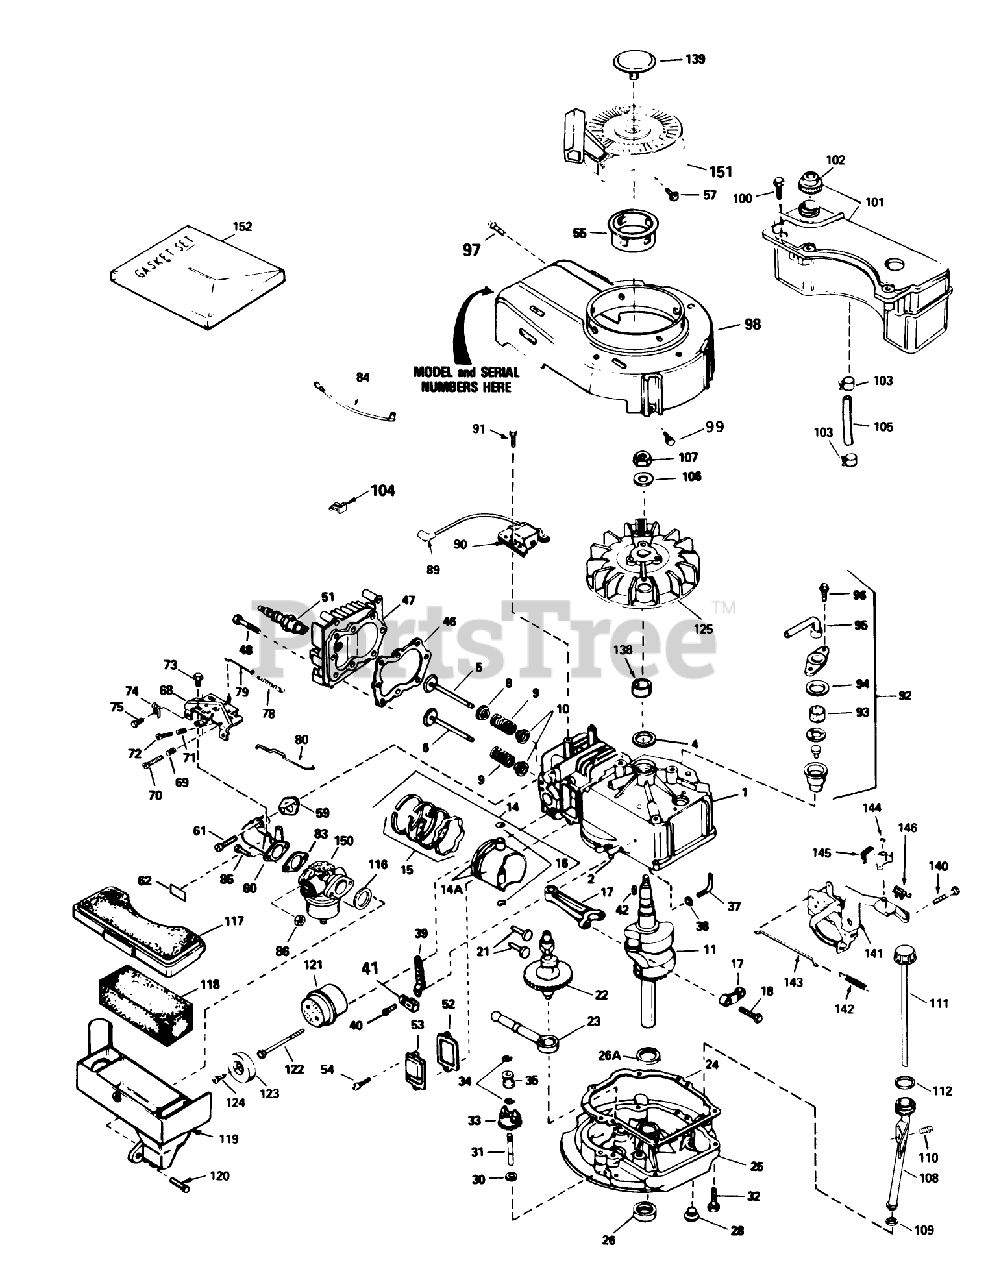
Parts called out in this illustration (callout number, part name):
1	Cylinder Assy. (Incl. #24)
2	Pin-Dowel
4	Seal-Oil
5	Valve, Intake (Std.) (Incl. Ref. #40)
5	Valve, Intake (1/32" oversize)(Incl. No. 40)
6	Valve, Exhaust (Std.)(Incl. No. 40)
6	Valve, Intake (1/32" oversize)(Incl. No. 40)
8	Seal Assy., Intake
9	Spring-Valve
10	Cap-Valve, Spring
11	Crankshaft
14	Piston-Pin Ring Assy. (Std.)(Incl. Ref. #16A, 17 18)
14	Piston-Pin Ring Assembly (.010 oversize)(Incl. Ref. #16A, 17 18)
14	Piston, Pin Ring Assy. (.020 Oversize)(Incl. Ref. #13A, 14, 15)
14A	Piston Pin Assy. (Std.)(Incl. Ref. #14)
14A	Piston Pin Assembly (.010 oversize)(Incl. Ref. #18)
14A	Piston Pin Assy. (.020 Oversize) (Incl. Ref. #14)
15	Ring Set-Piston (Std.)
15	Ring Set, Piston(.0100versize)
15	Ring Set (.020" OS)
16	Ring-Retaining, Piston Pin
17	Rod Assy., Connecting (Incl. Ref. #17)
18	Bolt-Rod, Connecting
21	Lifter-Valve
22	Camshaft(Mech.Comp. Release)
23	Oil Pump ASM
24	Gasket
25	Flange-Mounting (Incl. Ref. #26, 27 39)
26	Seal-Oil
26A	Washer-Thrust
28	Plug Oil Drain
30	Washer-Flat
31	Shaft-Governor
32	Screw (1/4-20 x 1-1/4)
33	Governor Gear ASM
34	Ring-Retaining
35	Spool-Governor
37	Rod, Governor (Incl. No. 36)
38	Washer-Flat
39	Governor Lever
40	Screw
41	Clamp-Lever, Governor
42	Key-Flywheel
46	63573 GIL 42 SNWTHW
47	Head-Cylinder
48	Screw
51	Spark Plug-Resistor (R J19 L M)
52	Gasket-Breather
53	Cover-Valve
54	Screw
55	Hub-Starter
57	Screw, Hex Hd.
59	Gasket-Intake
60	Pipe-Intake (Incl. Ref. #59)
61	Screw (1/4-20 x 1)
62	Decal-Primer
68	51089 SUPP TO MANUA
69	61709/GIL1515A/95-5
70	Screw
71	Spring-Compression
72	Screw
73	Screw (10-24 x 9/16)
74	Conduit
75	Screw (10-32 x 3/8)
78	Spring Governor
79	2035A67 ADD.ASSEMBL
80	Link-Throttle
83	Gasket
84	Ground Wire
86	Nut and Lock Washer (1/4-28)
89	Cover-Spark Plug
90	Solid State
91	Screw
92	Breather Assy. (Incl. Ref. #46 thru 51)
93	Element-Breather
94	Gasket-Breather
95	Tube, Breaker
96	Screw (10-24 x 9/16)
97	Screw (10-24 x 9/16)
98	Housing-Blower
99	Screw (1/4-20 x 1/2)
100	Screw (10-32 x 35/64)
101	Tank Assembly-Fuel (Incl. Ref. #102)
102	Cap-Fuel
103	Clamp-Line, Fuel
104	Clip-Wire
105	Line-Fuel
106	Washer-Belleville
107	Nut-Flywheel
108	Oil Fill Tube
109	Gasket
110	Screw (10-32 x 1/2)
111	Dipstick
112	O-Ring
116	Gasket-Cleaner, Air
117	Cover-Air Cleaner
118	Filter-Air Cleaner
119	Body Air cleaner
120	Screw
121	Muffler (Incl. Ref. #122)
122	Screw
123	Cover-Muffler
124	Screw (8-32 x 3/8)
125	Flywheel
138	Spacer
139	Plug Starter
140	Screw (1/4-20 x 3/8)
141	Bracket-S.E. Brake
142	Spring-Extension
143	Link-Control
144	Ring-Retaining
145	Lever-Brake
146	Terminal
150	Carburetor (Incl. Ref. #83)
151	Starter-Rewind
152	Gasket Set
